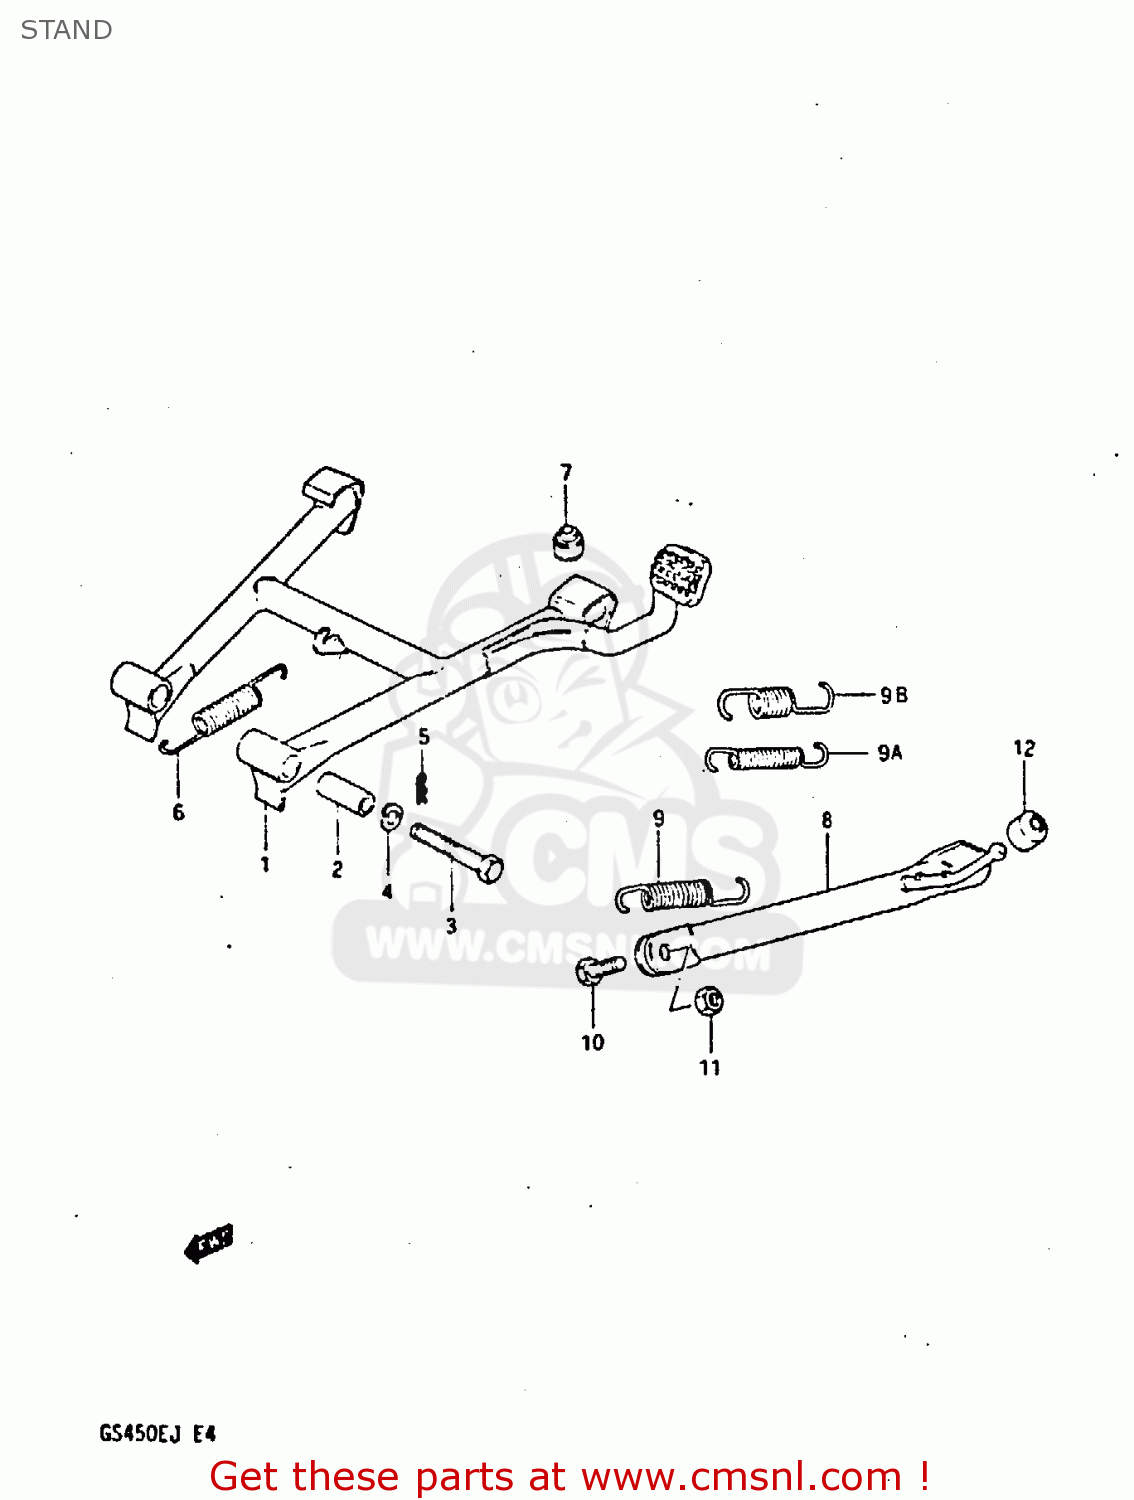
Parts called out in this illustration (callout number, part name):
1	STAND,CENTER
2	SPACER(10X16X38.8)
3	BOLT
4	WASHER,LOCK,10
5	CLIP
6	SPRING
7	CUSHION
8	STAND, PROP
9	SPRING
9A	SPRING
9B	SPRING
10	BOLT L:30
11	NUTM10X1.25X8
12	CUSHION
